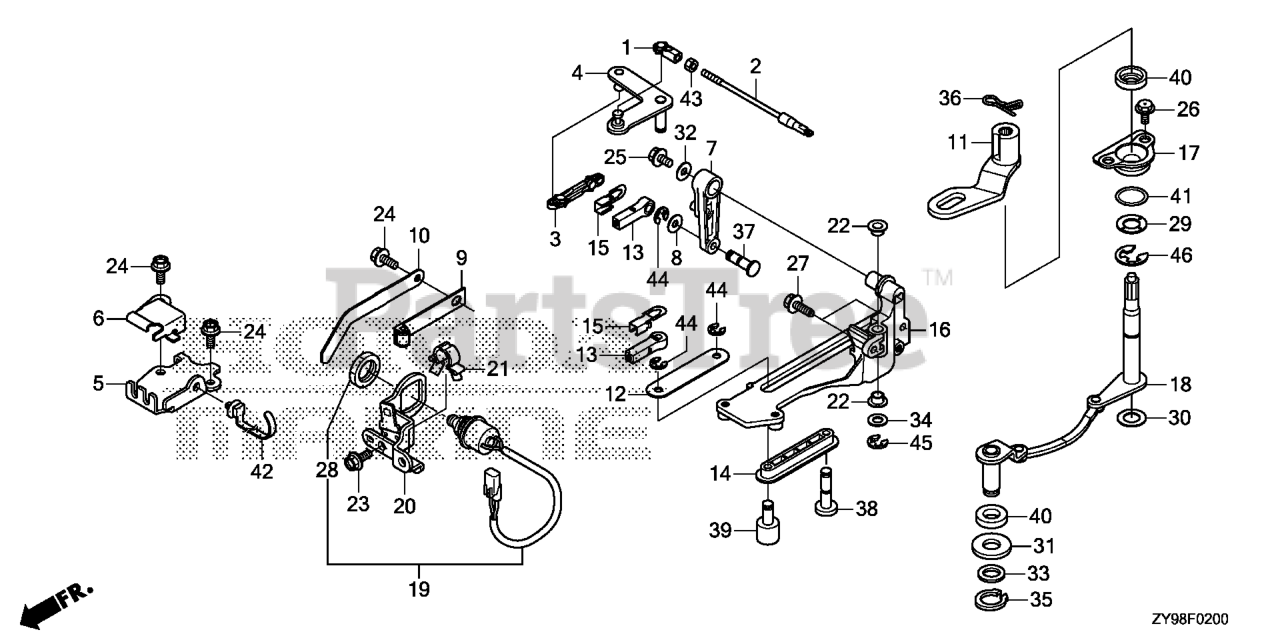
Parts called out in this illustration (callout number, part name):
1	LINKAGE, PIVOT
2	ROD, THROTTLE
3	LINK, THROTTLE
4	PLATE, THROTTLE
5	PLATE, REMOTE CONTROL CABLE
6	COVER, REMOTE CONTROL CABLE
7	ARM, THROTTLE
8	WASHER, PIVOT
9	SPRING, CLICK
10	SPRING, CLICK ASSIST
11	ARM, SHIFT
12	PLATE, SHIFT PIVOT
13	PIVOT, SHIFT
14	PIVOT, SHIFT SLIDE
15	PLATE, LOCK
16	BRACKET, SHIFT LINK
17	HOLDER, SEAL
18	SHAFT, SHIFT
19	SWITCH ASSY., NEUTRAL
20	BRACKET, NEUTRAL SWITCH
21	CLIP, BRAKE PIPE (A) (FOR NEUTRAL SWITCH)
22	BUSH A, COVER LOCK
23	BOLT, FLANGE (6X14) (CT200)
24	BOLT, FLANGE (6X16)
25	BOLT, FLANGE (6X12)
26	BOLT, FLANGE (6X11)
27	BOLT, FLANGE (6X18) (CT200)
27	BOLT (6X18) (CT200)
28	NUT, HEX. (20MM) Use up to Frame SN 1300359.
29	WASHER, SIDE (14MM)
30	WASHER, SHIFT SHAFT
31	WASHER (14MM)
32	WASHER, PLAIN (6MM)
33	WASHER (13MM)
34	WASHER, PLAIN (8MM) Use from Frame SN 4800713.
35	CIRCLIP (OUTER) (12)
36	PIN, SNAP (6MM)
38	PIN, SHIFT LINK
40	SEAL, WATER (14X26X6)
41	O-RING (27X2) (ARAI)
42	CLIP, HARNESS BAND (155.3MM) (BLACK)
43	NUT, HEX. (5MM)
44	E-RING (4MM)
45	E-RING (6MM)
46	E-RING (12MM)
